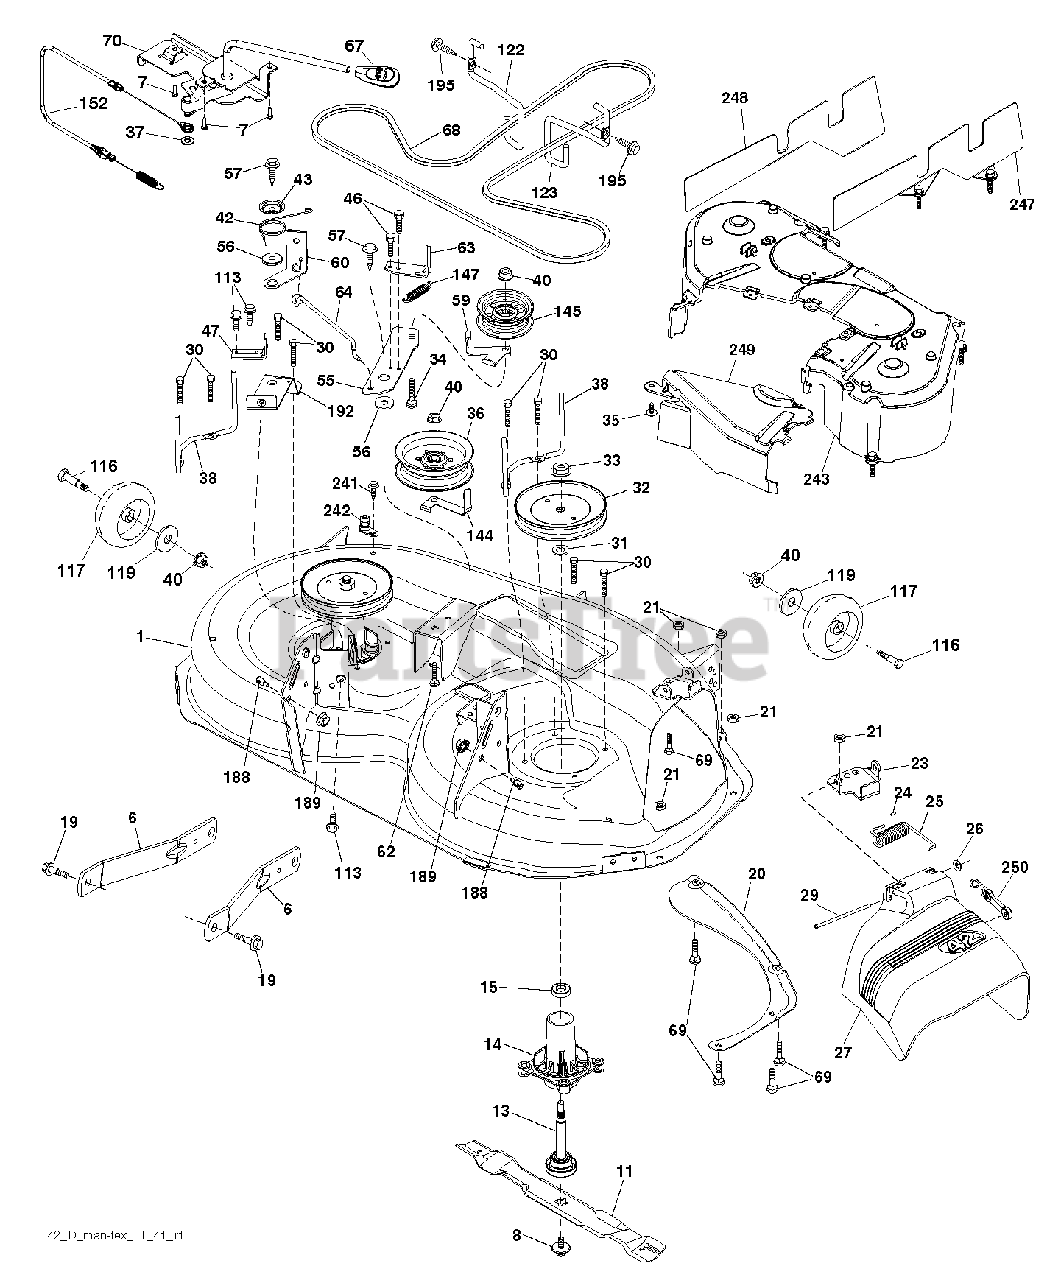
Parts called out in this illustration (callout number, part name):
1	DECK.WELDMENT.42"
6	ARM.SUSPENSION.MOWER.R
7	SCREW.#10 X 0.750.BOS THREAD
8	BOLT.WASHER.ASM.7/16-2
11	42" HI-LIFT BLADE
13	SHAFT.ASM.MDRL.N/GREASE.38
14	HOUSING MANDREL
19	BOLT.SHOULDER
20	BAFFLE.VORTEX
21	LOCKNUT
23	BRKT.DEFLECTOR.38"2005+
24	CAP-SLEEVE LT
25	SPRING.TORSION.DEFLECT
26	NUT PUSH M
29	ROD.HINGE
30	SCREW, WASHER HEAD
31	WASHER.SPACER.MANDREL
32	PULLEY.MANDREL.5.438.PD
33	NUT.FLANGE.LOCK.TOP
34	BOLT.3/8-16X1.50
35	FASTENER.XMAS.TREE
36	PULLEY.IDLER.2006
38	KEEPER.BELT.MANDREL.PULLEY
40	NUT LOCK FLG 3/8-16 UNC
42	SPRING.TORSION.BRAKE
43	SRPING.TORSION.RETAINE
46	SCREW.1/4-20X5/8
47	BRKT.CLUTCH.CABLE
55	IDLER.ARM.42"
56	SPACER.RETAINER
57	SCREW 3/8-16X1
59	GUARD, BELT
60	ARM BRAKE MOWER
62	BOLT
63	ARM BRAKE MOWER
64	LINK BRAKE
67	HANDLE.CLUTCH.CABLE.LT
68	BELT.DECK.DRIVE.42"
69	BOLT
70	CLUTCH.ASM.MANUAL.YT.PREDATORQ
113	BOLT.5/16HEX.WHS.HD
117	WHEEL.GAGE.HALF.SPOKED
119	WASHER
122	KEEPER BELT ENGINE LH
123	KEEPER BELT RH
144	KEEPER.BELT.MOWER
145	PULLEY.IDLER.48"PRIMARY
147	RETURN SPRING
152	CABLE.CLUTCH.MANUAL.
188	STUD.FASTNER.W/ANTI-ROTATE
189	NUT LOCK HEX FLANGE 5/16-18
192	BRKT.BRAKE.STAND.LH.
195	SCREW, 3/8-16X3/4
242	PORT.WASHOUT
